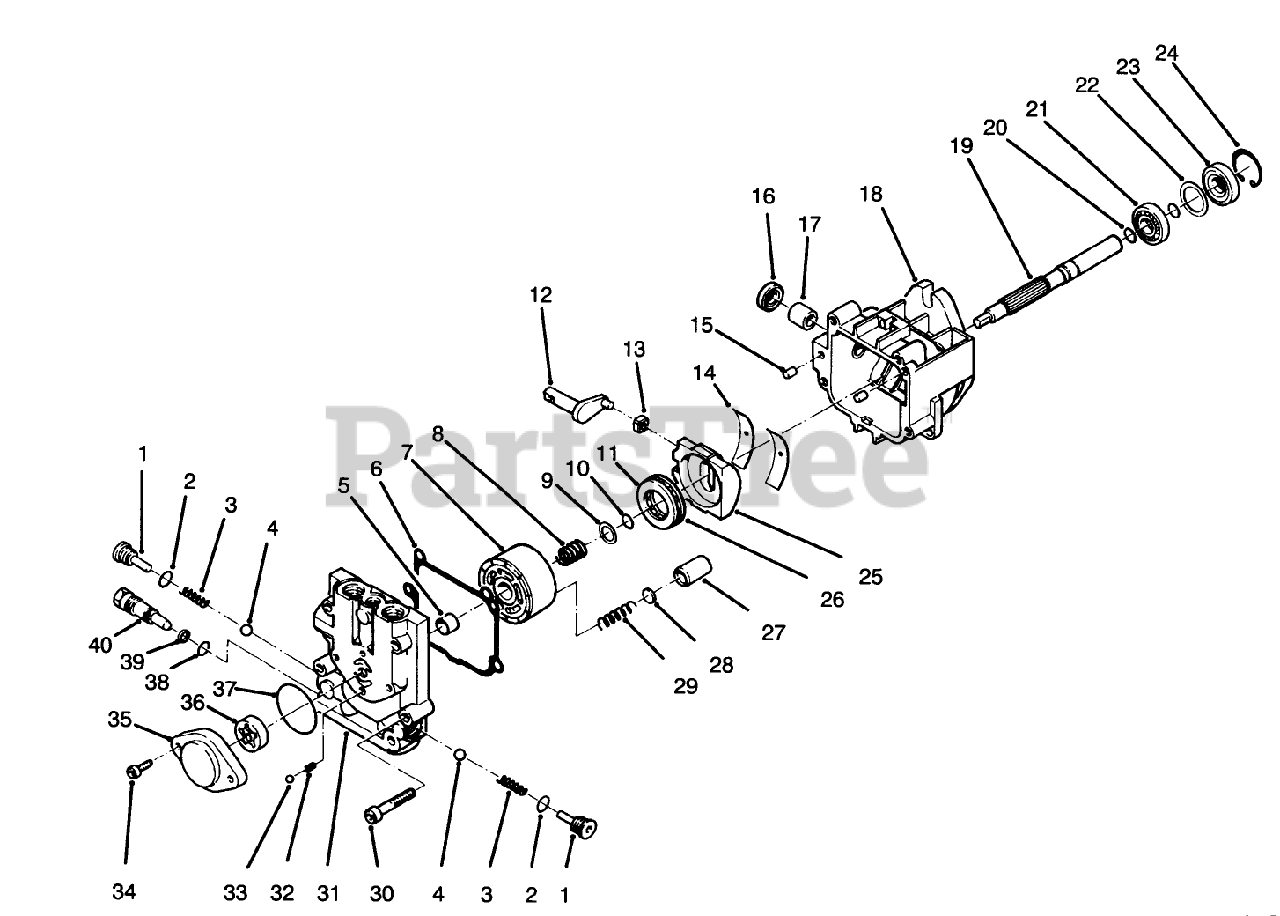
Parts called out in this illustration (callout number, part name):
1	CHECK VALVE KIT
2	Seal-O-Ring
3	Loose Parts Package
4	Loose Parts Package
5	Journal-Bearing
6	Gasket-End Cap
8	Loose Parts Package
9	Loose Parts Package
10	Loose Parts Package
11	Plate-Thrust
12	Arm-Trunnion
13	Guide-Slot
14	Cradle-Bearing
15	Loose Parts Package
16	Seal-Lip
17	Journal-Bearing
19	Shaft
20	Loose Parts Package
21	Bearing-Ball
22	Loose Parts Package
23	Seal-Lip
24	Loose Parts Package
25	Swashplate Assembly
26	Roller-Thrust
27	Loose Parts Package
28	Loose Parts Package
29	Spring-Piston
30	Loose Parts Package
32	Ball
33	Loose Parts Package
34	Loose Parts Package
35	Housing-Charge Pump
36	Gerotor Assembly
37	Seal-O-Ring
38	Seal-O-Ring
39	Ring-Back-Up
40	Valve-Bypass
